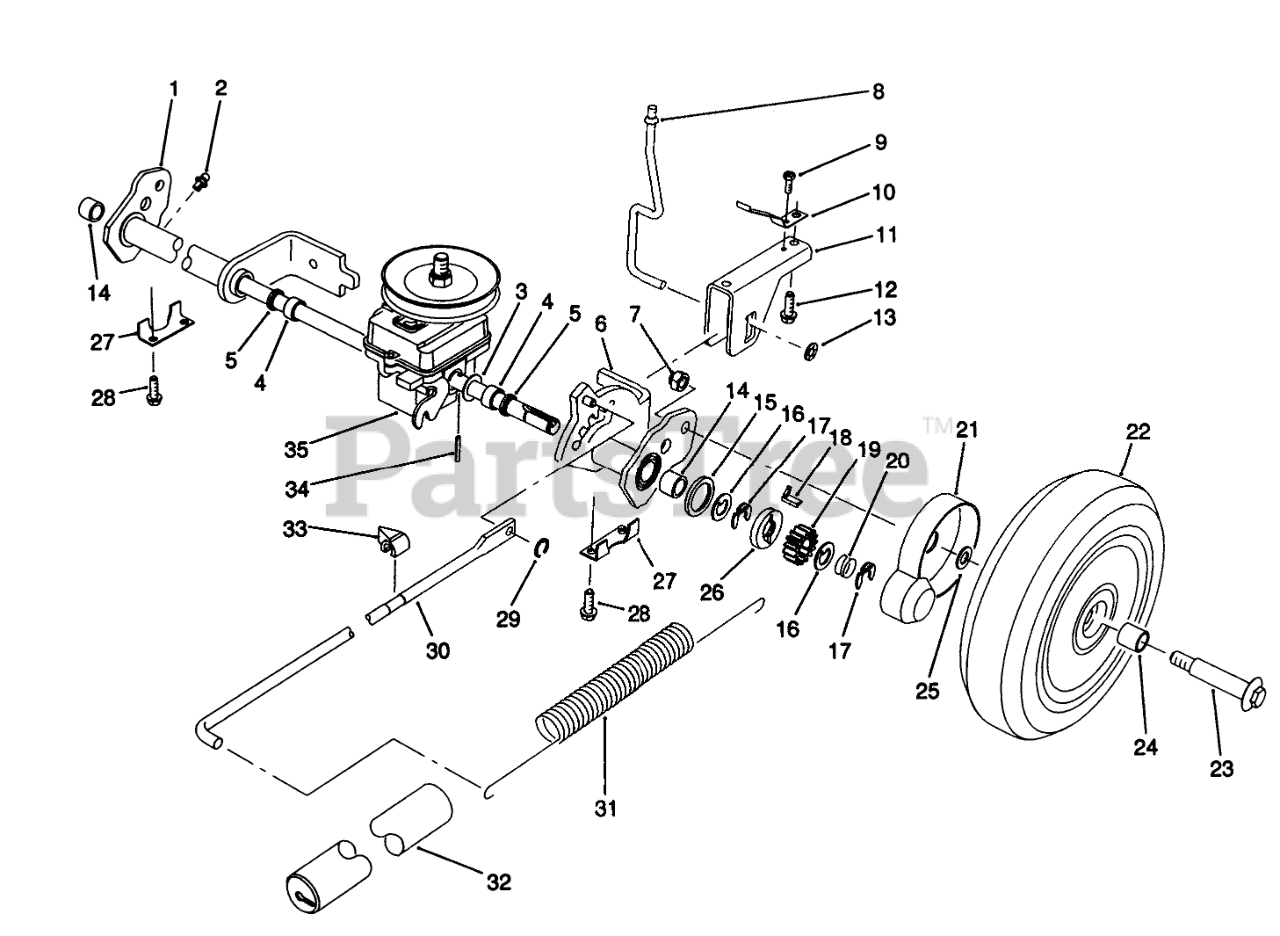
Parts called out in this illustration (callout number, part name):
1	Rear Pivot Assembly R.H. (Incl. Ref. #2,4,5 & 14)
2	Fitting-Grease
3	WASHER-PLAIN
4	BUSHING
5	SEAL-OIL
6	Rear Pivot Assembly L.H. (Incl. Ref. #2,4,5 & 14)
7	Nut
8	TRIGGER ROD
9	SCREW 8 - 32 X 250
10	SPRING - TRIGGER RET
11	SADDLE - HOC
12	SCREW
13	PUSHNUT
14	BEARING-ROLLER
15	RING-FRICTION
16	WASHER-THRUST, KEYED
17	RING-CLIP, LOCKING
18	KEY-ROCKING, LH
19	GEAR-PINION
20	SPRING-COMPRESSION
21	COVER-WHEEL
22	Wheel, Tire & Gear Assy. (Incl. Ref. #24)
23	BOLT-WHEEL
24	BUSHING
25	SPACER-COVER, WHEEL
26	WASHER-CLUTCH
27	REAR SECURING PLATE
28	SCREW-HWHTF
29	GRIP RING
30	LINK ROD
31	SPRING-COUNTERBALANCE
32	COVER-SPRING
33	INDICATOR-HEIGHT OF CUT
34	COIL PIN
35	Gearbox Assembly
